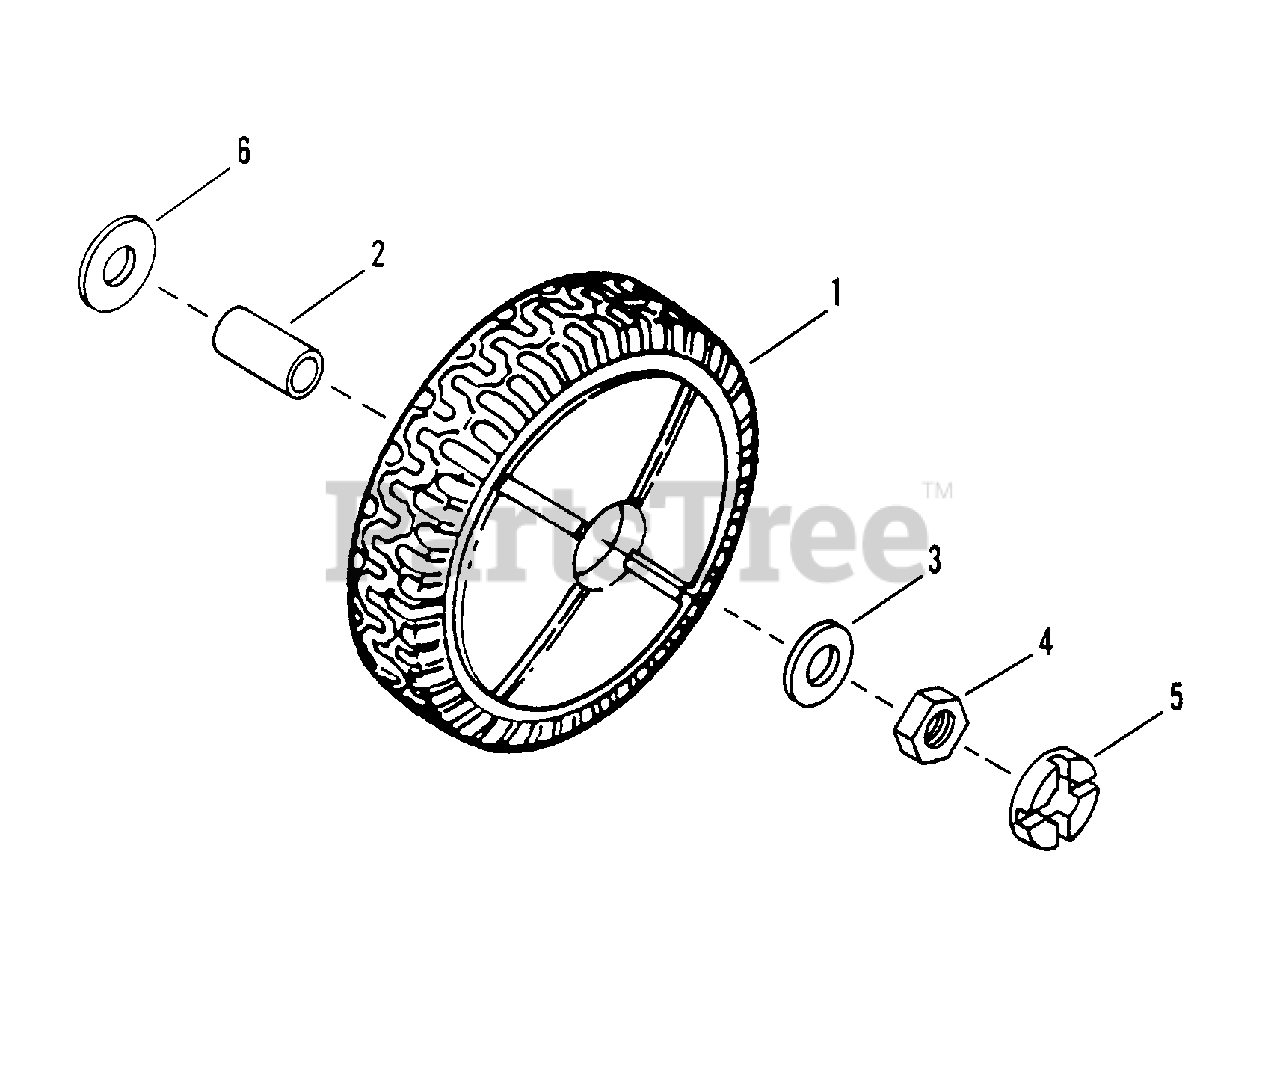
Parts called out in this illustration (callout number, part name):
1	WHEEL, 8 x 2.00, Plastic
2	BUSHING, Axle
3	WASHER, 7/16" ID x 1" OD SAE
4	NUT, 7/16-20 Hex (Thin)
5	PLUG, Wheel
6	WASHER, 1" O.D., Flat
